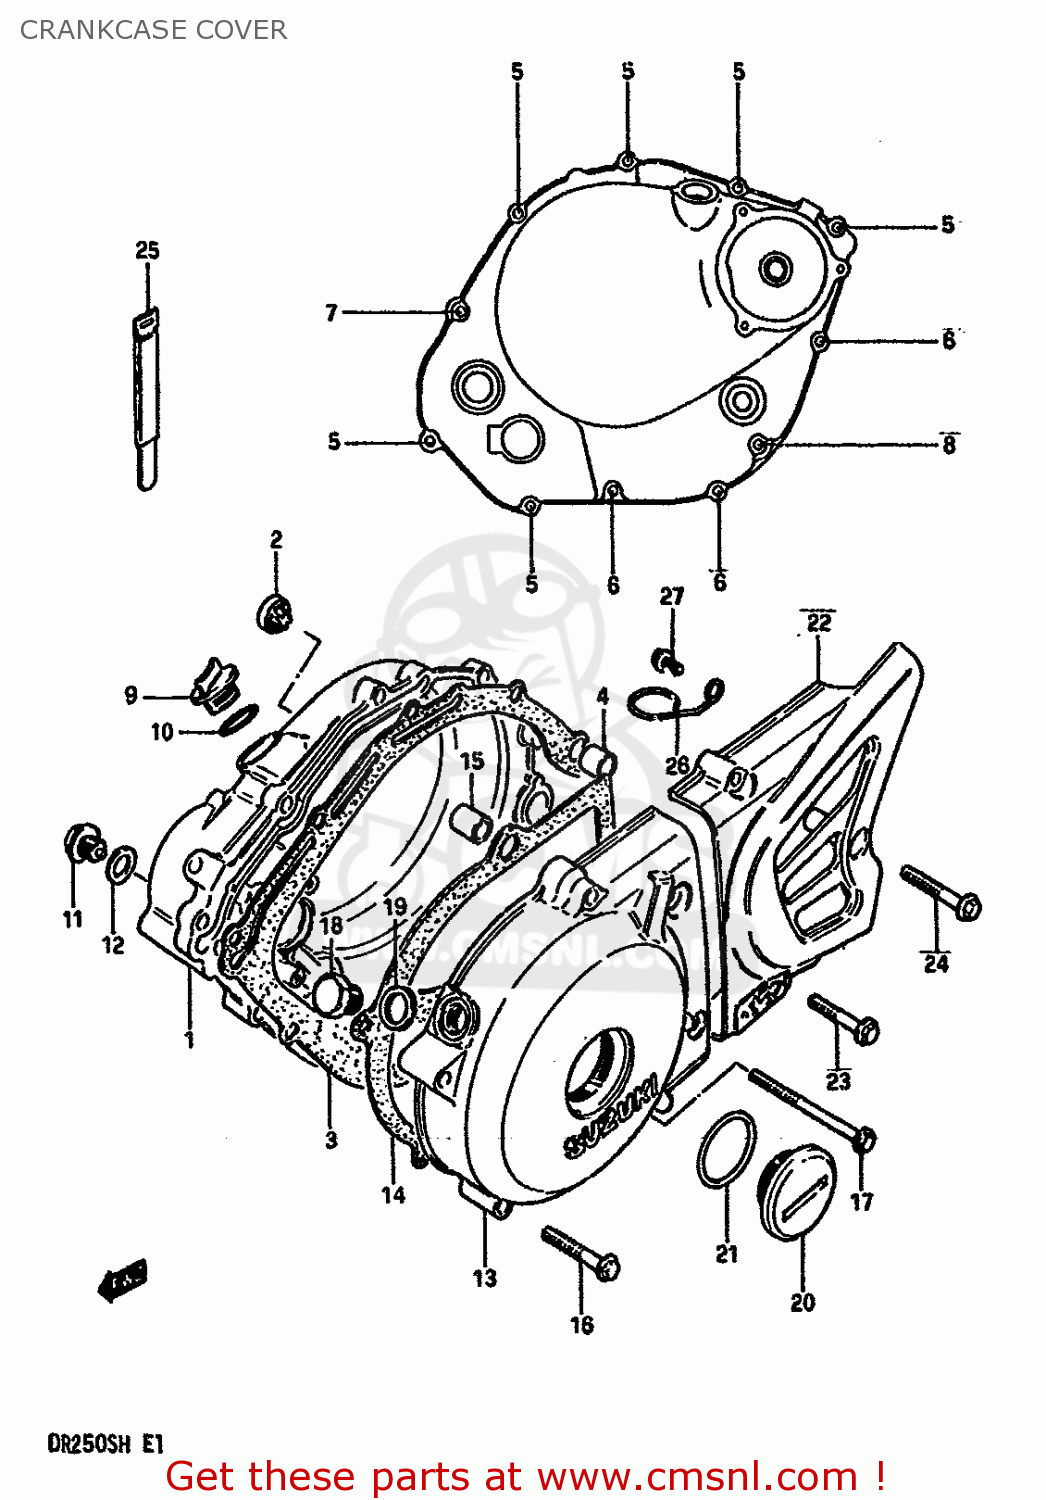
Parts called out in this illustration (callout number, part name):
1	COVER,CLUTCH
2	LENS,OIL LEVEL CHECK
3	GASKET,CLUTCH COVER (MCA)
4	PIN
5	BOLT 6X25
6	BOLT 6X35
7	BOLT 6X40
8	BOLT
9	PLUG
10	O RING(D:3.1,ID:16.8)
11	PLUG(14X12)
12	GASKET(14X19.2X2) (NAS)
13	COVER
14	GASKET,MAGNETO COVER (MCA)
15	PIN
16	BOLT 6X35
17	BOLT 6X50
18	PLUG(12X9)
19	GASKET(12.1X16.2X3.7) (NAS)
20	PLUG
21	O RING(D:3.1,ID:32.7)
22	COVER,SPROCKET
23	BOLT 5X30
24	BOLT (5X35)
25	CLAMP L:110
26	GUIDE
27	BOLT
